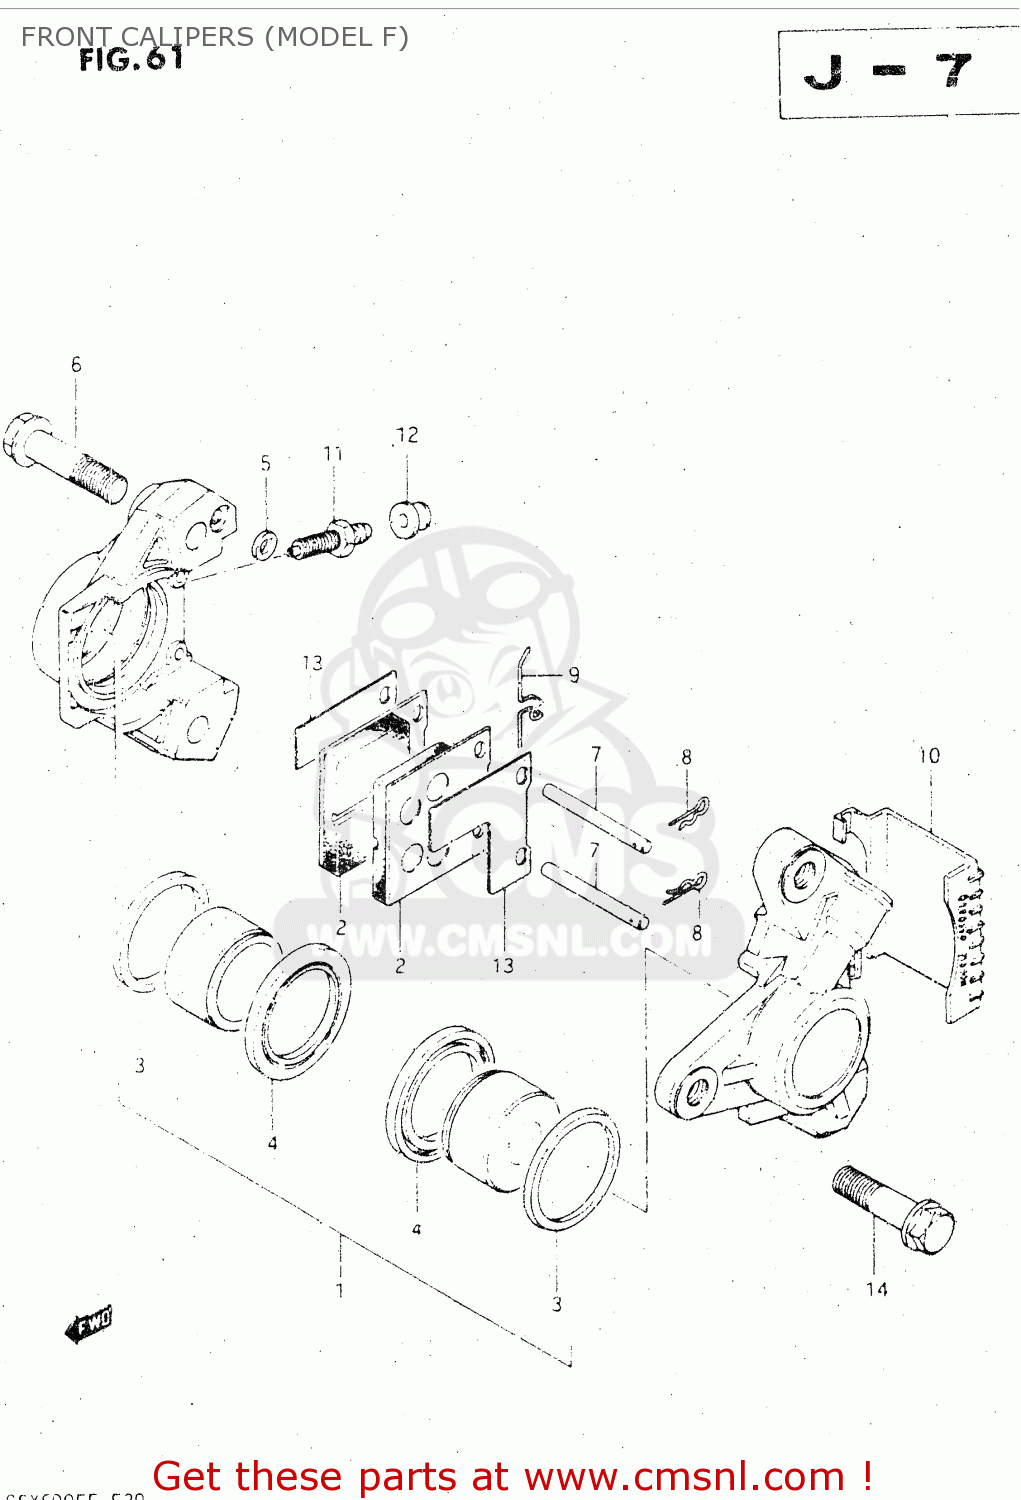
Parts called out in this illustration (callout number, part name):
1	PISTON SET
2	PAD
3	SEAL,PISTON
4	BOOT
5	SEAL,JOINT
6	BOLT,HOUSING
7	PIN,PAD
8	CLIP,PAD PIN
9	SPRING
10	COVER,CALIPER
11	BLEEDER
12	CAP,BREATHER
13	SHIM
14	BOLT 10X37
